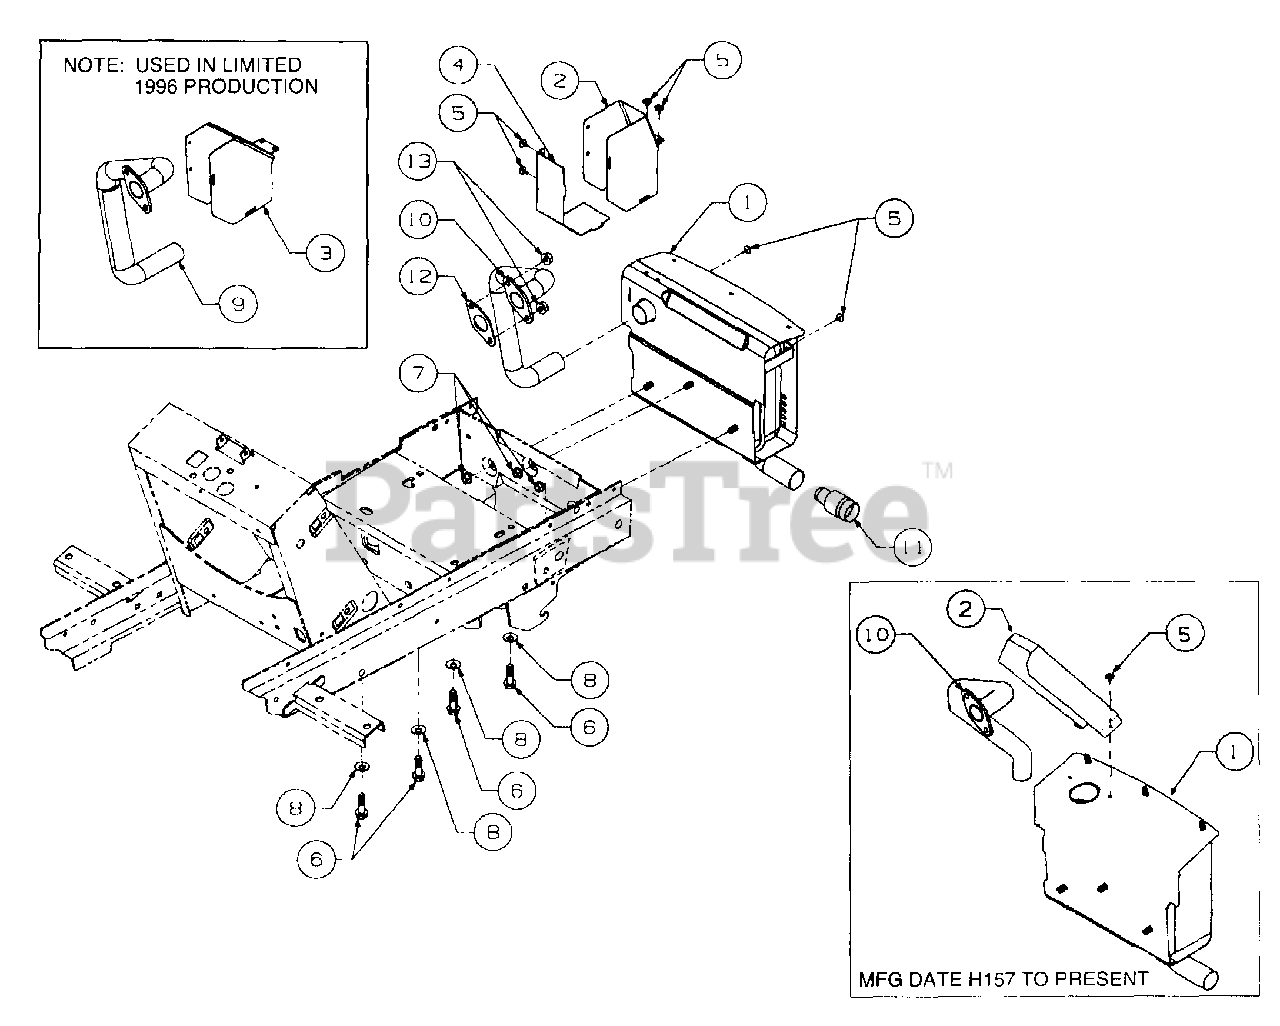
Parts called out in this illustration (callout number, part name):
1	Muffler Assembly
2	Shield, Exh.
3	Shield, Exh.
4	Shield, Exhaust Tube Rear
5	Screw, Hex Wash Hd Tapp #10-16 x .38
6	Screw, Engine Mounting 3/8-16 x 1.25
7	Nut, Hex Flange Lock, 5/16-18
8	Washer, Bell, .380 x .88 x .062
9	Tube, Exaust, w/Attached Heat Baffle
10	Tube, Exh.
11	Arrestor, Spark
12	Gasket, Exhaust (Same as KH-12-041-03)
13	Nut, Exhaust, M8 x 1.25 (Same as KH-M-0841080)
